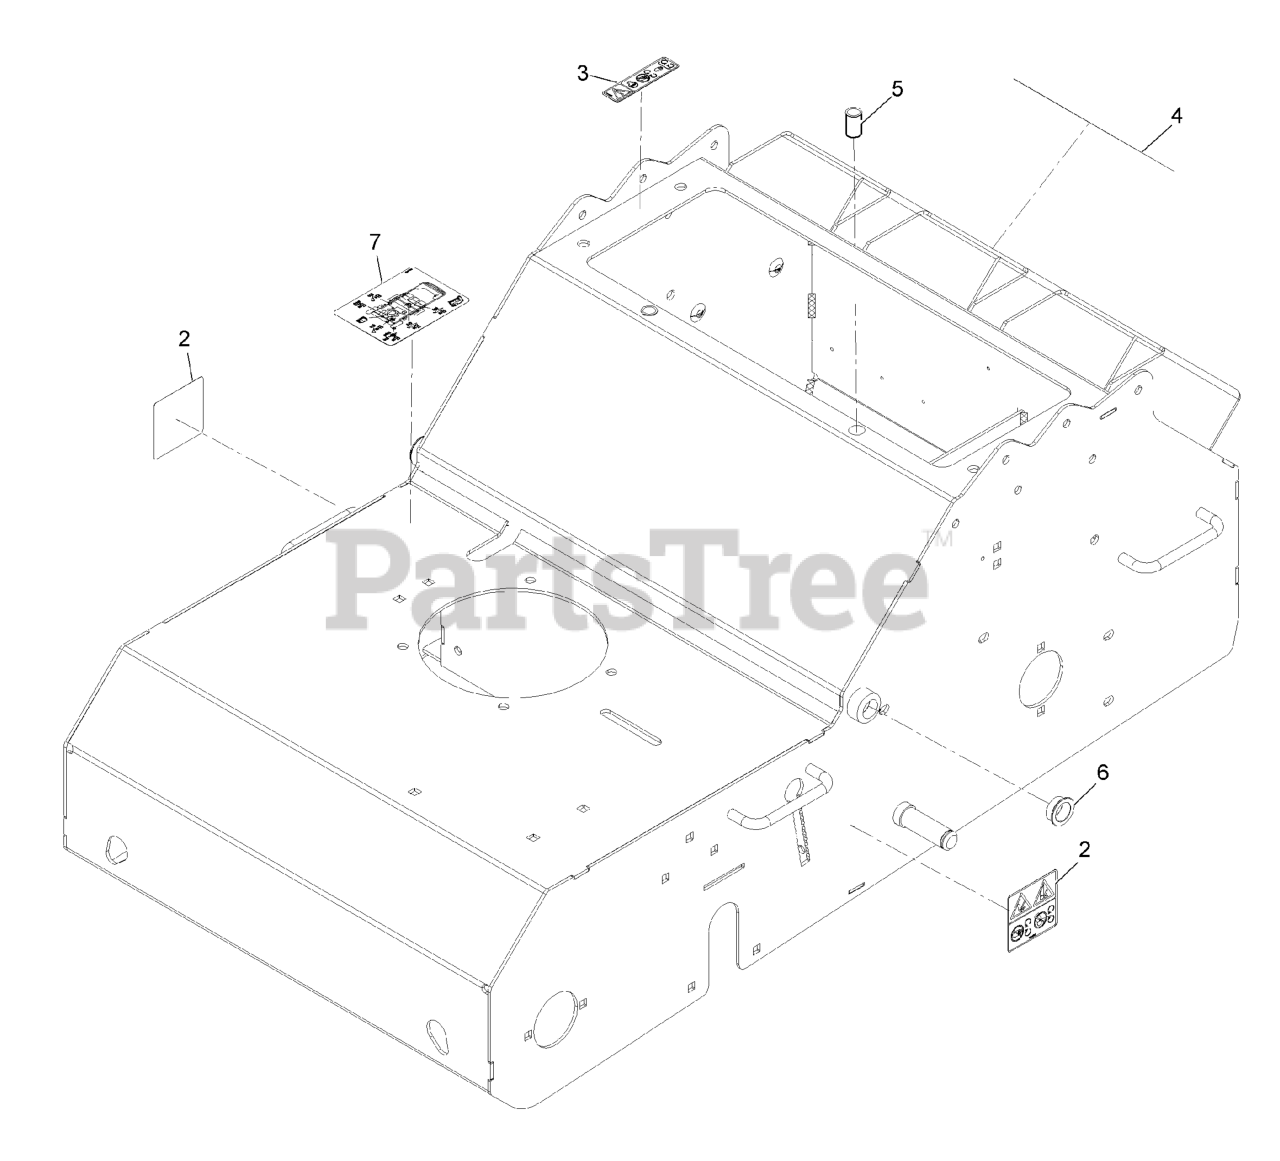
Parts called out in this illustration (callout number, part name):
2	DECAL-WARNING
3	DECAL-DANGER
4	Decal-Warning Aerator 21
5	NUT-CLINCH
6	BUSHING-BRONZE
7	Decal-Service Aid 21 Aerator
